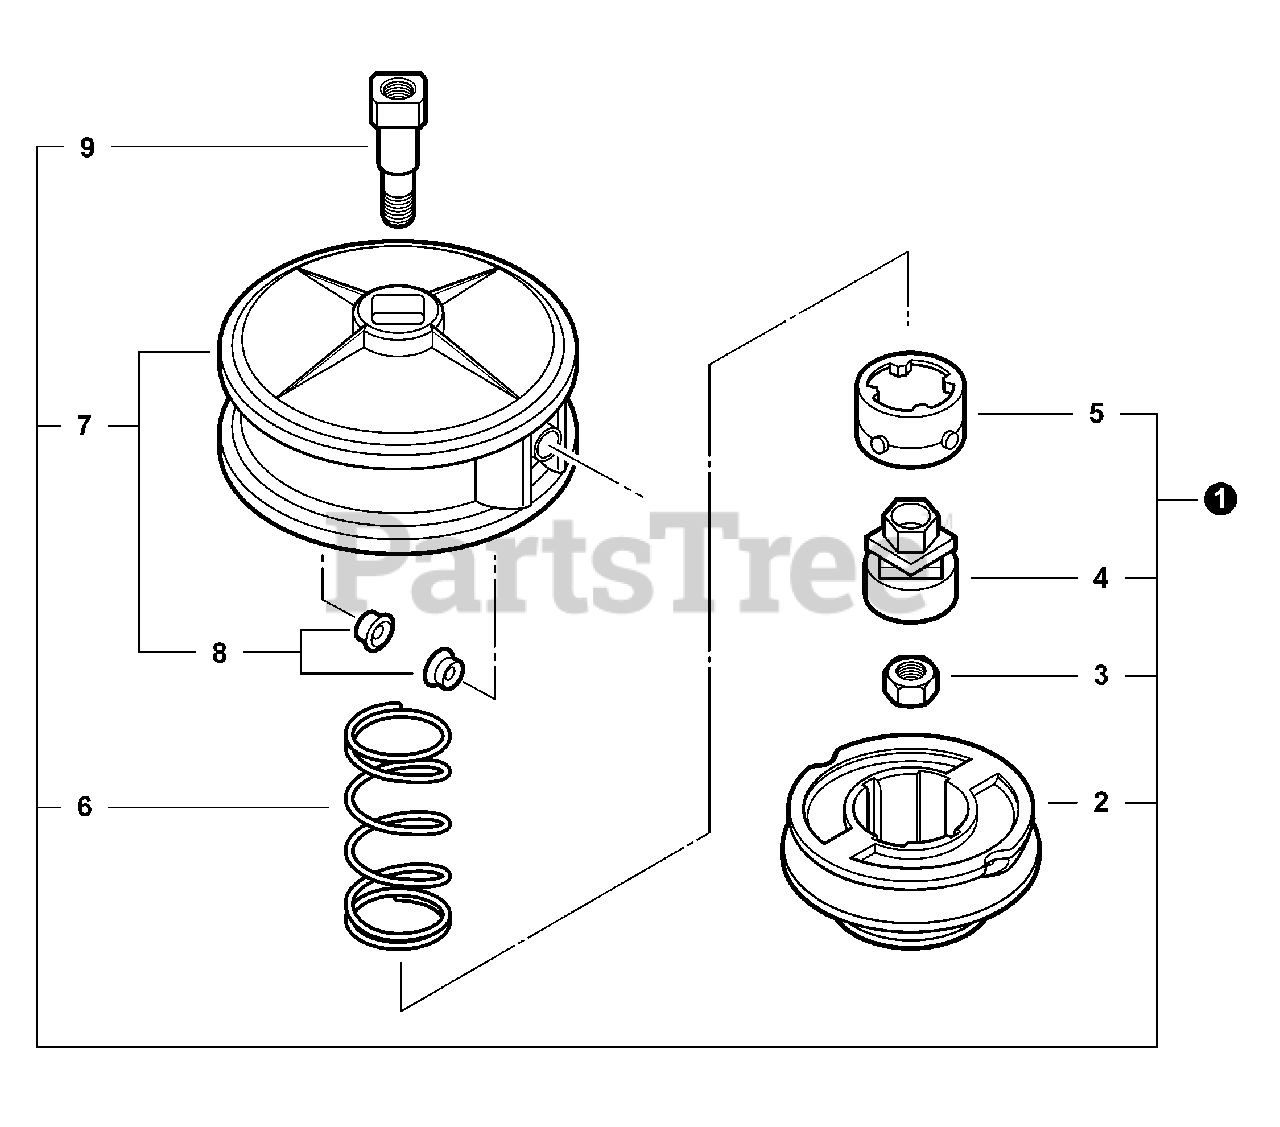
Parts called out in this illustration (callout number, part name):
1	U-TURN HEAD
4	CAM, INNER
5	DRIVE, OUTER
7	HOUSING
9	BOLT, SHAFT
